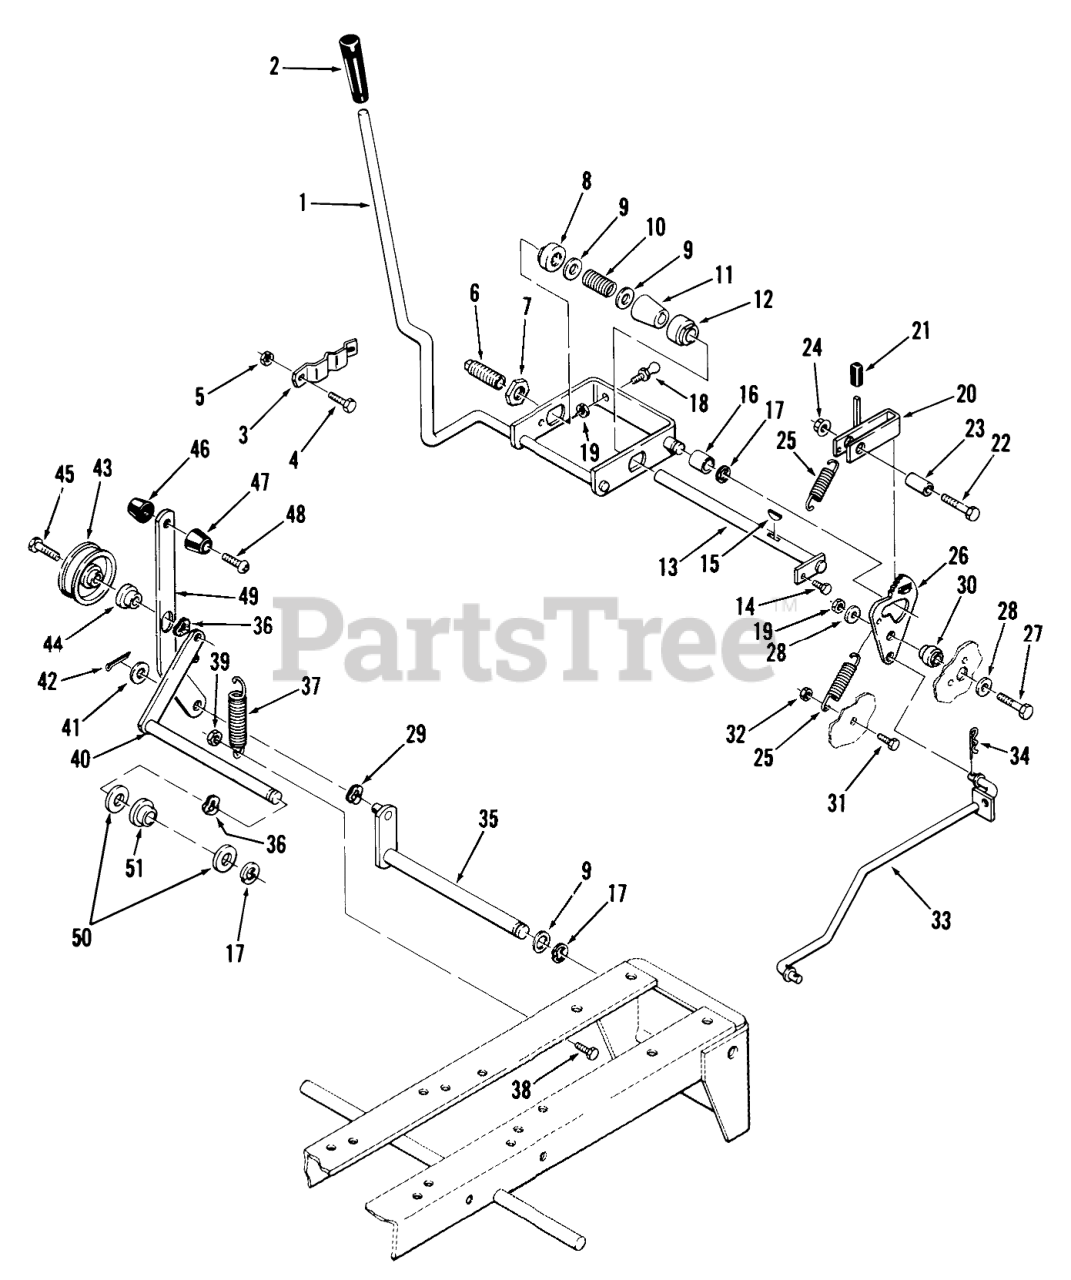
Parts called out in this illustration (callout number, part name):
1	Motion Control Lever
2	KNOB
3	Detent-Motion Control Lever
4	H H C S
5	Nut
6	Collar Friction
8	COLLAR BRKT PIVOT
9	Washer
10	SPRING FRICTION
11	FRICTION CONE
12	FRICTION COLLAR
13	ASSY-CAM PIVOT ROD
14	SCREW
15	WOODRUFF KEY
16	BEARING-CAM RETURN
17	E Ring
18	PIN
19	Nut
20	PAWL HDL ASSY B
21	VALVE LEVER GRIP
22	BOLT
23	SPACER
24	LOCKNUT-FLANGE
25	Spring
26	Cam Plate
27	Bolt
28	Washer
29	WASHER-WAVE
30	Spacer
31	Bolt
32	Nut
33	Brake Rod-Front
35	ASSY-BRAKE LEVER
36	WASHER-WAVE
37	SPRING-EXTENSION
38	Bolt
39	Nut
40	ASSY-ARM/ROD WA
41	Washer
42	Cotter Pin
43	Idler Pulley
44	SPACER-BRAKE LINK
45	Bolt 3/8-16 x 1 1/2 Special
46	KNOB
47	KNOB
48	BOLT-4
49	Handle
50	Washer
51	BUSHING-FLANGED
